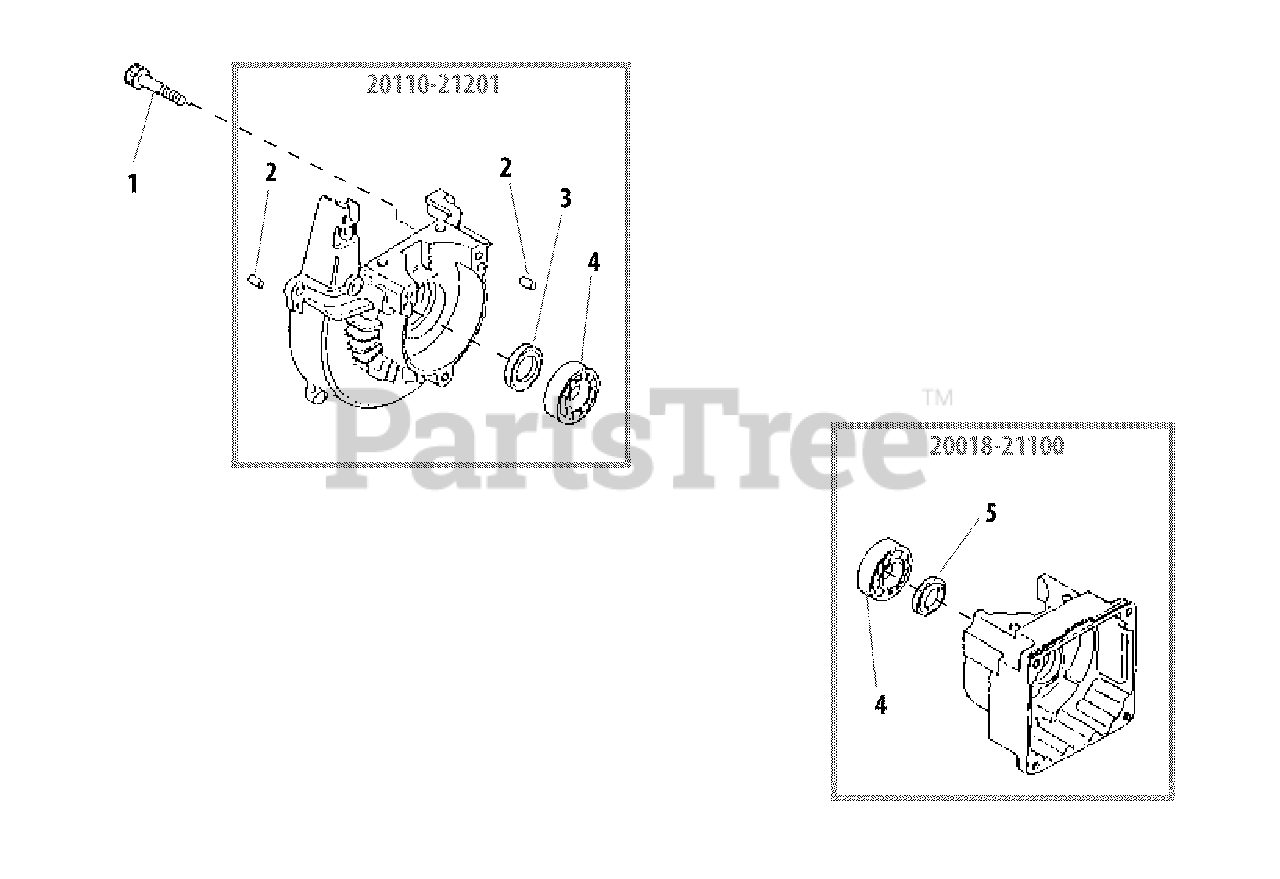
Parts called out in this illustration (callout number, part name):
1	BOLT 5×25
2	PIN, LOCATING Ø4×8
3	SEAL, OIL 12
4	BEARING, BALL 6001 C3
5	SEAL, OIL 12
A	CRANKCASE ASSY, M
A	CRANKCASE ASSY, S
